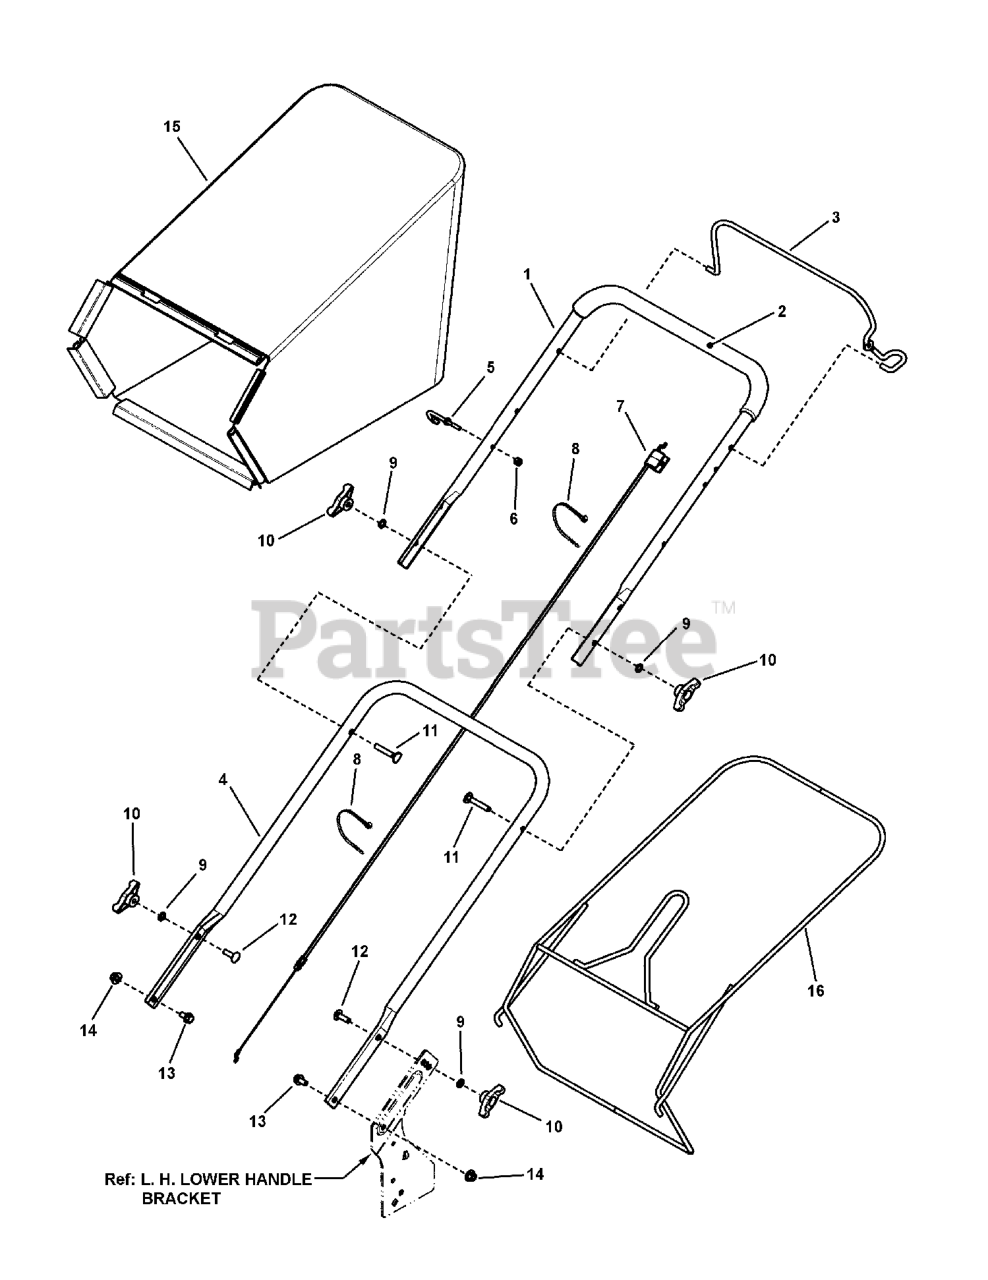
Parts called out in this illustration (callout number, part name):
1	HANDLE, Upper
2	FOAM GRIP, 18.75" (on upper handle)
3	BAIL, OPC Push
4	HANDLE, Lower
5	GUIDE, Rope (1/4-20 thread)
6	NUT, 1/4-20 Nyloc
7	CABLE, Bail (48.38" overall length)
8	WIRE TIE, 11" Std Black Nylon
9	WASHER, 5/16" Internal Tooth Lock
10	KNOB, 5/16-18 Wing (Black)
11	BOLT, 5/16-18 x 2" Curved Head Square Neck, GR 2
12	BOLT, 5/16-18 x 1" Round Head Square Neck Carriage, GR 5 YZ
13	BOLT, 5/16-18 x 5/8" Hex Flange Lock, GR 5
14	NUT, 5/16-18 Large Head Center Lock
15	GRASS BAG, 22" Rear Discharge
16	FRAME, Bag, 22" WBM
